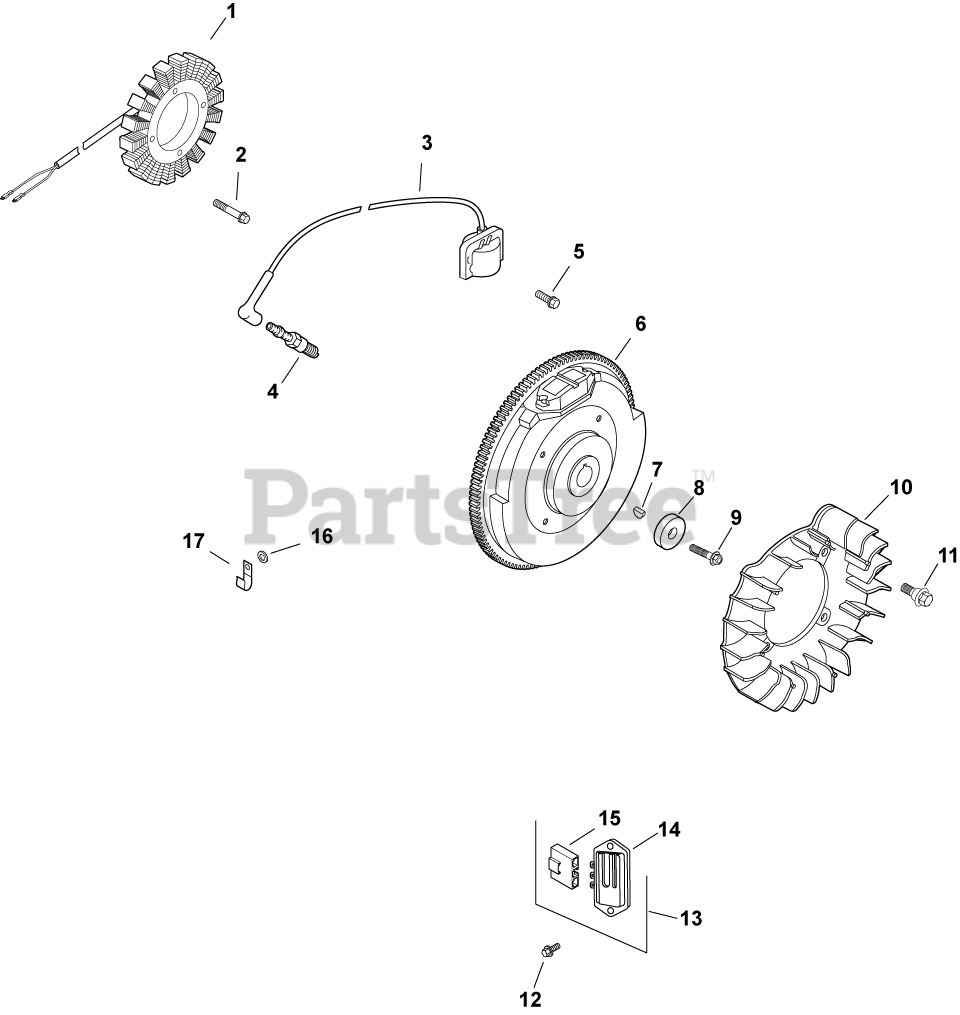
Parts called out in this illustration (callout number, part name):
1	KIT, 25 AMP STATOR ASSY.
2	SCREW, THD FROM M5X0.8X30
3	KIT, MODULE IGNTN (CDI FIXED)
4	PLUG, SPARK (STD)
5	SCREW, FLG THD FRM M5X.8X20-(#25086399S)
6	FLYWHEEL ASSEMBLY
7	KEY, 3/16" X 5/8"
8	WASHER, FLAT 13/32"
9	SCREW, FLG M10X1.5X45 - (#25086361S)
10	FAN USE 24 755 253-S
11	BOLT, SHOULDER
12	SCREW, HEX FLANGE HI-LO
13	KIT, FULL WAVE CONVERSION
14	REG/RECTIFIER (20/25 AMP)-USE 25 403 20-
15	CONNECTOR, BODY (KM)-USE 25 155 41-S
16	WASHER, FLAT 1/4" (O.D. 1/2")
17	CLIP, CABLE
